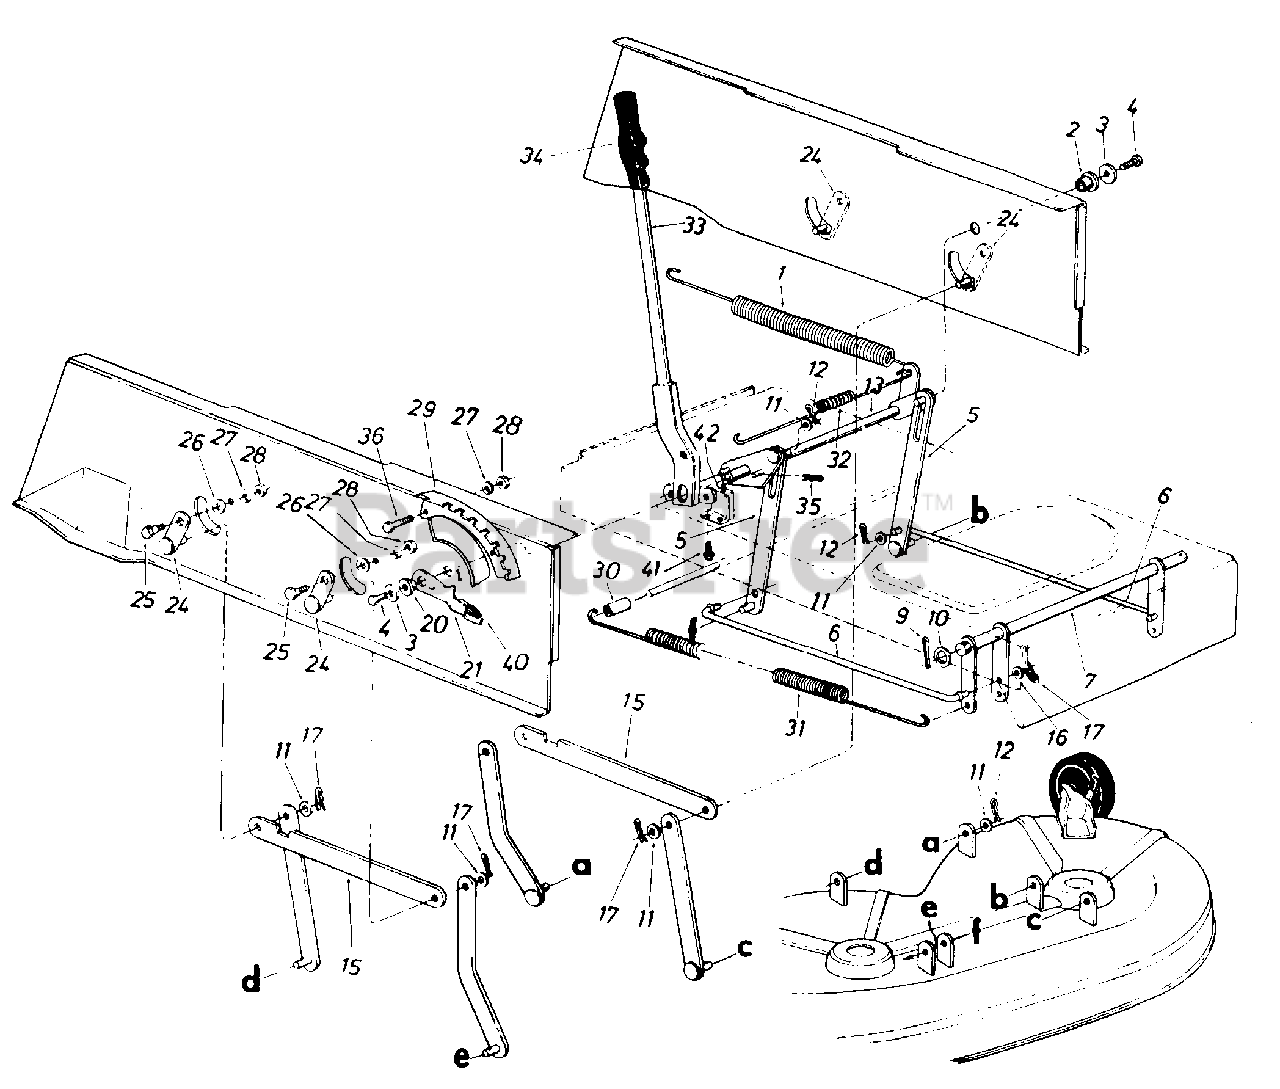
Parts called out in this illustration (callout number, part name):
1	Extension Spring .99" O.D. x 11.00" Lg.
2	Flange Bearing .634" I.D.
3	Fl-Wash. .344" I.D. x 1.125"
4	Hex Wash. Hd. 5/16-18 x .62" Lg.
5	Link Deck Lift Ass'y.
6	Stabilizer Rod
7	Stabilizer Shaft Ass'y.
9	Cotter Pin 1/8" Dia. x 1-1/4"
10	Fl-Wash. .635" I.D. x 1.12"
11	Fl-Wash. .531" I.D. x .940"
12	Inter. Cotter Pin
13	Lift Shaft Ass'y.
15	Connecting Rod
16	Fl-Wash. .40" I.D. x .88"
17	Inter. Cotter Pin 3/8" Rod
20	Flange Brg. .630" I.D.
21	Deck Lift Down Stop
24	Pivot Link Ass'y.
25	Shld. Bolt .437" Dia. x .180" Lg. (5/16-18)
26	Fl-Wash. .344" I.D. x .62"
27	L-Wash. 5/16" I.D.
28	Hex Nut 5/16-18 Thd.
29	Index Brkt.
30	Spacer .523" I.D. x .640" O.D. x 1.95" Lg.
31	Ext. Spring .99" O.D. x 1 3.25 Lg.
32	Ext. Spring .56" O.D. x 32 Coils
33	Lift Handle Ass'y.
34	Grip
35	Intern. Cotter Pin 1/2" Dia.
36	Hex Bolt 5/16-18 x .75"
41	Hex AB-Tap Scr. #10 x .50"
42	Safety Switch
